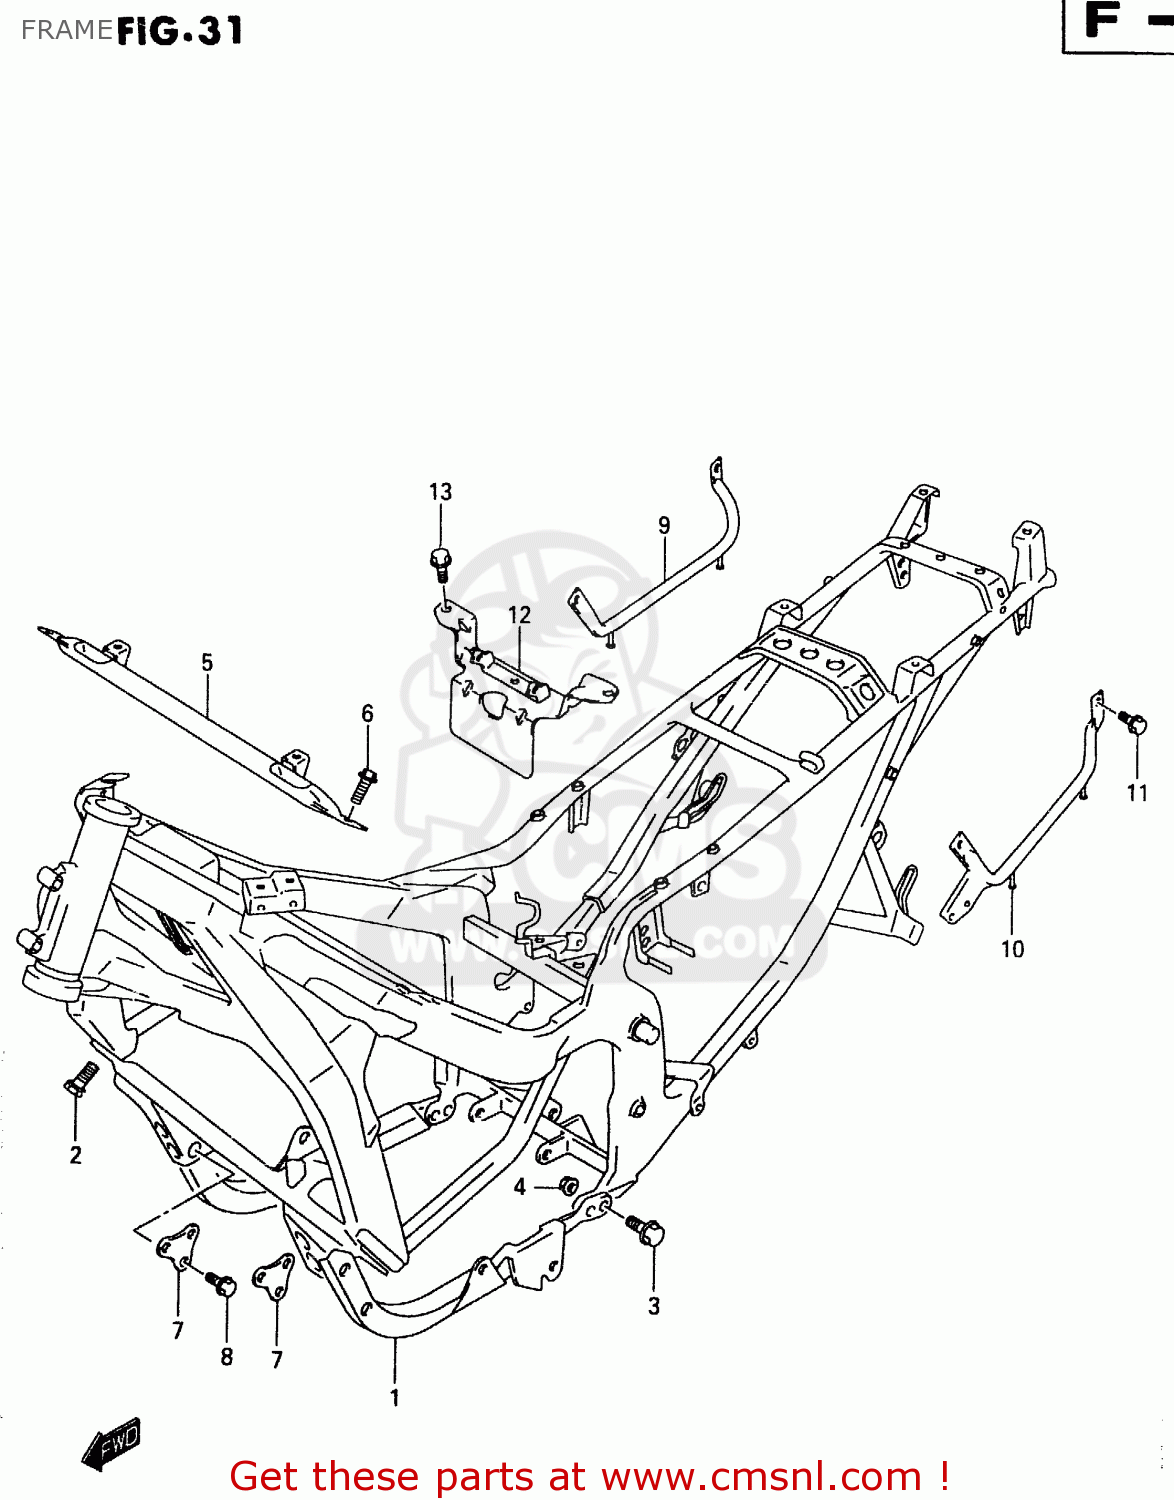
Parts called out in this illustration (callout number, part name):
1	FRAME(BLACK)
2	BOLT
3	BOLT
4	NUT
5	TUBE,FRAME BRIDGE NO.2
6	BOLT(8X20)
7	PLATE,ENG MTG NO.1
8	BOLT, UPPER
9	GRIP,RR,R
10	GRIP,RR,L
11	BOLT
12	PLATE COMP,ELECTRIC PARTS
13	BOLT
